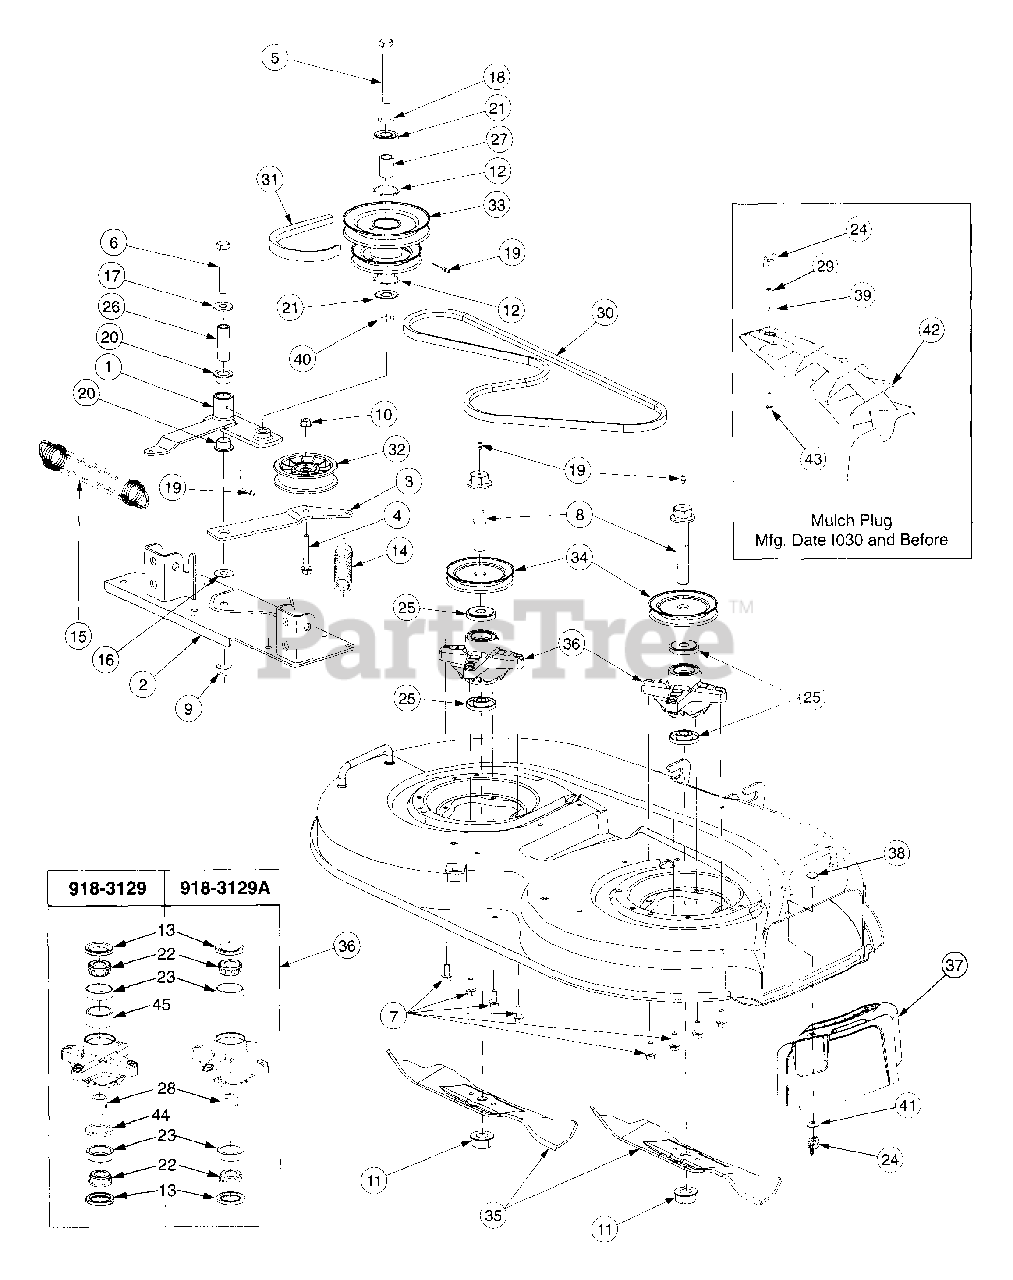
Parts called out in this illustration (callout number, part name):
2	Plate Assembly, Mounting
4	Screw, Hex Cap, 3/8-16 x 1.5 GR5
5	Screw, Hex Cap, 5/8-18 x 3.0 GR5
6	Screw, Hex Cap, 1/2-20 x 3.0 GR8
7	Screw, Hex Wsh Hd Tap, 5/16-18 x .75
8	Bolt, Spindle, 3/4-16 x 4.25
9	Nut, Hex Center Lock, 1/2-20
10	Nut, Hex Flange Lock, 3/8-16
11	Nut, Hex Flange, 3/4-16
12	Snap Ring, Internal
13	Seal, Oil, 1.25 x 1.874 x .25
14	Spring, Extension, .88 x 6.12
15	Spring, Extension, 1.25 x 8.15
16	Washer, Flat, .531 x 1.25 x .036
17	Washer, Flat, .531 x 1.25 x .100
18	Washer, Flat,
19	Fitting, 3/16 Drive Lube
20	Bearing, Flange, 3/4 ID x .53 Lg
21	Bearing, Ball, .62 ID x 1.57 OD
22	Cone, Bearing
23	Cup, Bearing
24	Nut, Wing, 1/4-20
25	Spacer, Deck Spindle
26	Spacer, Idlr Brkt .50 ID x .75 OD x 2.25
27	Spacer, Pulley.635 ID x .88 OD x 1.25
28	Spacer, Bearing, .780 x .963 x .777
29	Nut, Hex, 1/4-20
30	Belt, Spindle, A-Section x 61 Lg
31	Belt, PTO, B-Section x 112.4 Lg
32	Pulley, Flat Idler, 3.5 OD
33	Pulley, Double
34	V-Pulley, 4.0 Dia
35	Blade, 3 In One, 21.20 Lg
36	Spindle Assy.
37	Plug, Mulch
38	Screw, Carriage, 1/4-20 x .62
39	Washer, Flat, .28 x .74 x .063
40	Washer, Flat, .65 x 1.25 x .075 Hdn
41	Washer, Belleville, .265 x .75 x .062
42	Plug, Mulch
43	Screw, Hex Cap, 1/4-20 x 1.0 GR5
44	Spacer, Bearing
45	Spacer, Bearing, 1.5 x 1.7525 x .8275
